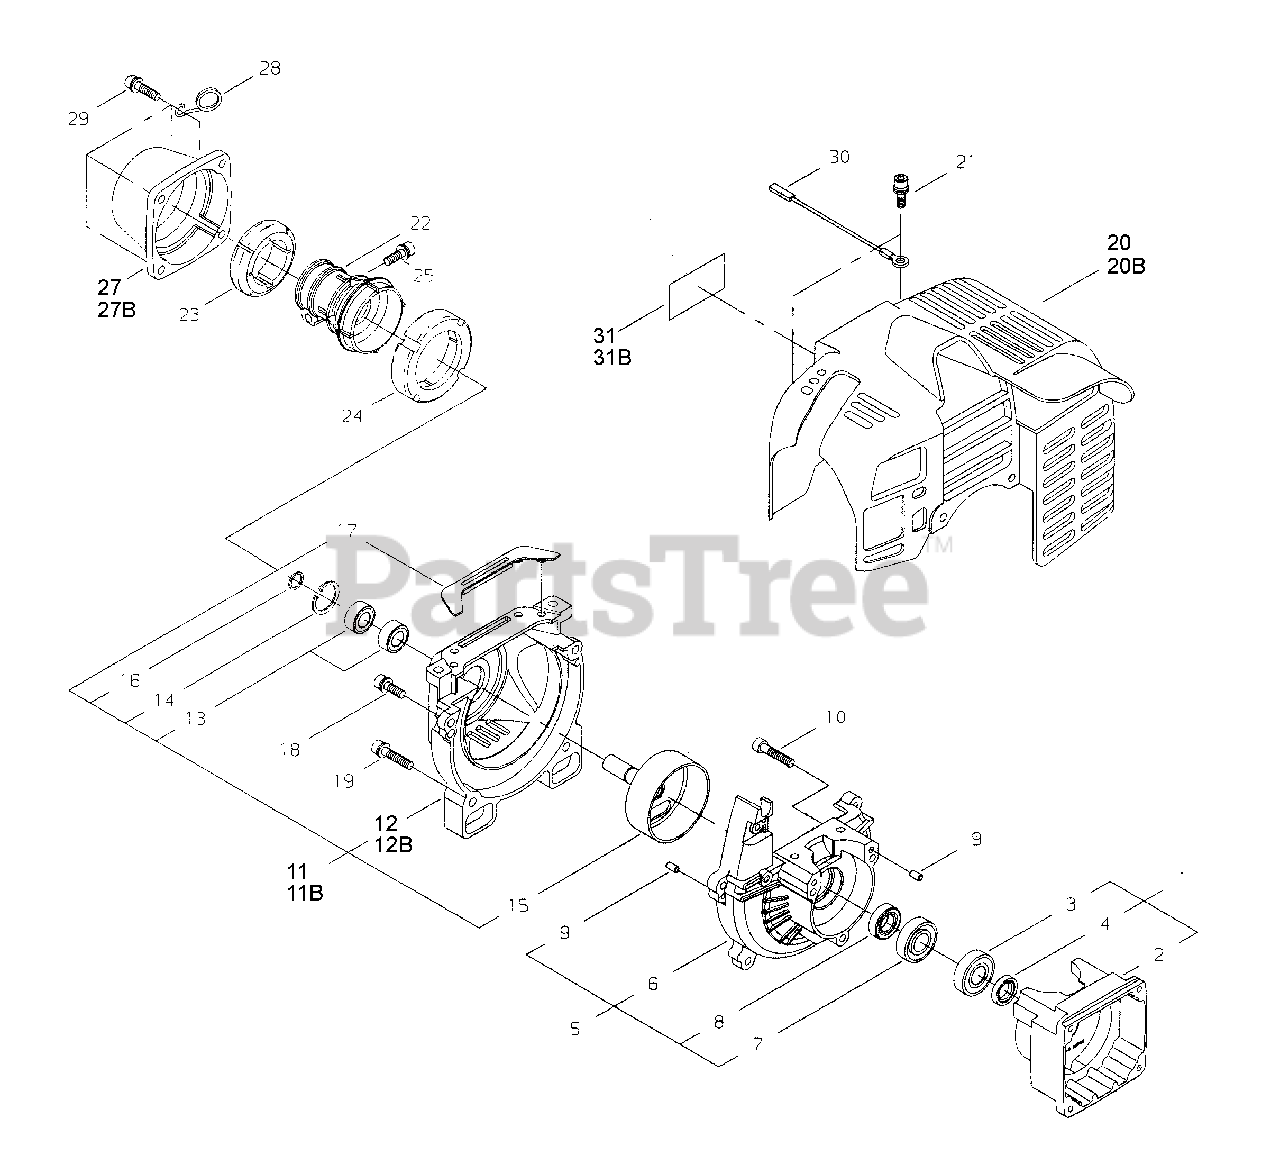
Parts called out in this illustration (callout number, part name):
1	CRANKCASE ASSY - REAR
2	CRANKCASE - REAR
3	BEARING, BALL - 6001C3
4	SEAL, OIL
5	CRANKCASE ASSY - FRONT
6	CRANKCASE - FRONT
7	BEARING, BALL - 6001C3
8	SEAL, OIL - 12
9	PIN - LOCATING
10	SCREW - 5X25
11	FAN CASE ASSY - RED
11B	FAN CASE ASSY - BLUE
12	CASE, FAN - RED
12B	CASE, FAN - BLUE
13	BEARING, BALL - 6000DDU
14	RING, RETAINING - 26
15	DRUM, CLUTCH
16	RING, RETAINING
18	SCREW - 5X16
19	SCREW - 5X30
20	COVER, ENGINE - RED
20B	COVER, ENGINE - BLUE
21	SCREW - 5X16
22	CLAMP, MAIN PIPE
23	CUSHION - FRONT
24	CUSHION - REAR
25	SCREW - 5X25
27	CAP
27B	CAP
28	GUIDE, CABLE
29	SCREW - 5X20
30	LEAD - GROUND
31	LABEL - MODEL
31B	LABEL - TRADE
